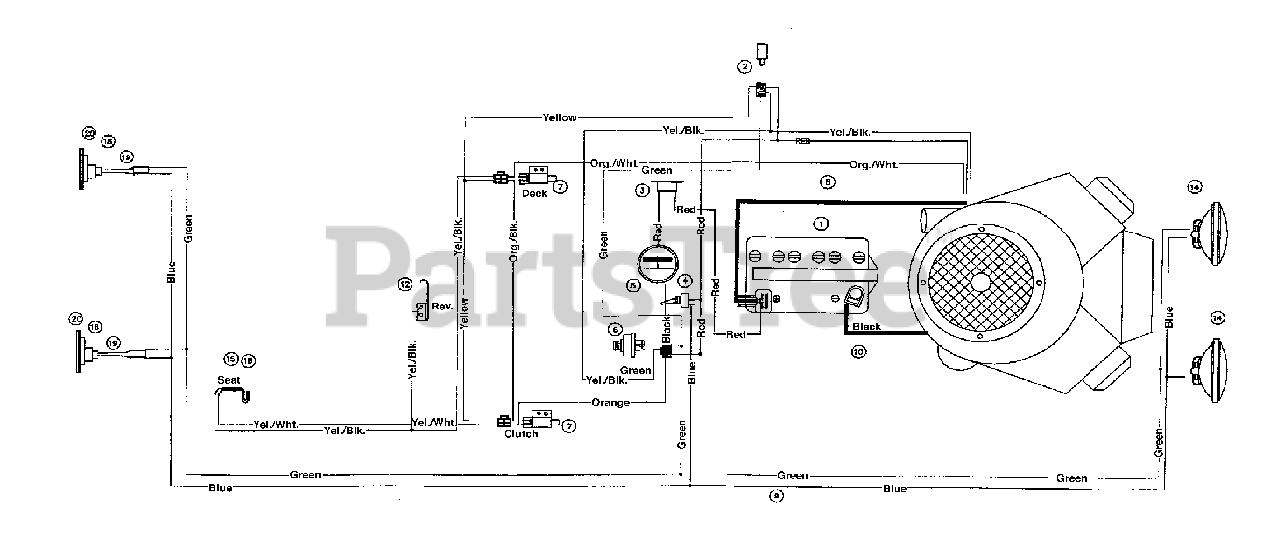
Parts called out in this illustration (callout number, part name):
1	Battery
2	Bosch Relay
5	Ammeter
6	Ignition Switch
7	Interlock Switch
8	Wire 6 Gage Red 32.5" Lg.
9	Harness
12	Reverse Safety Switch
14	Bulb, Headlight
15	Seat Safety Switch
16	Seat Safety Switch
18	Tail Light
19	Tail Light Harness
20	Bulb, Tail Light
